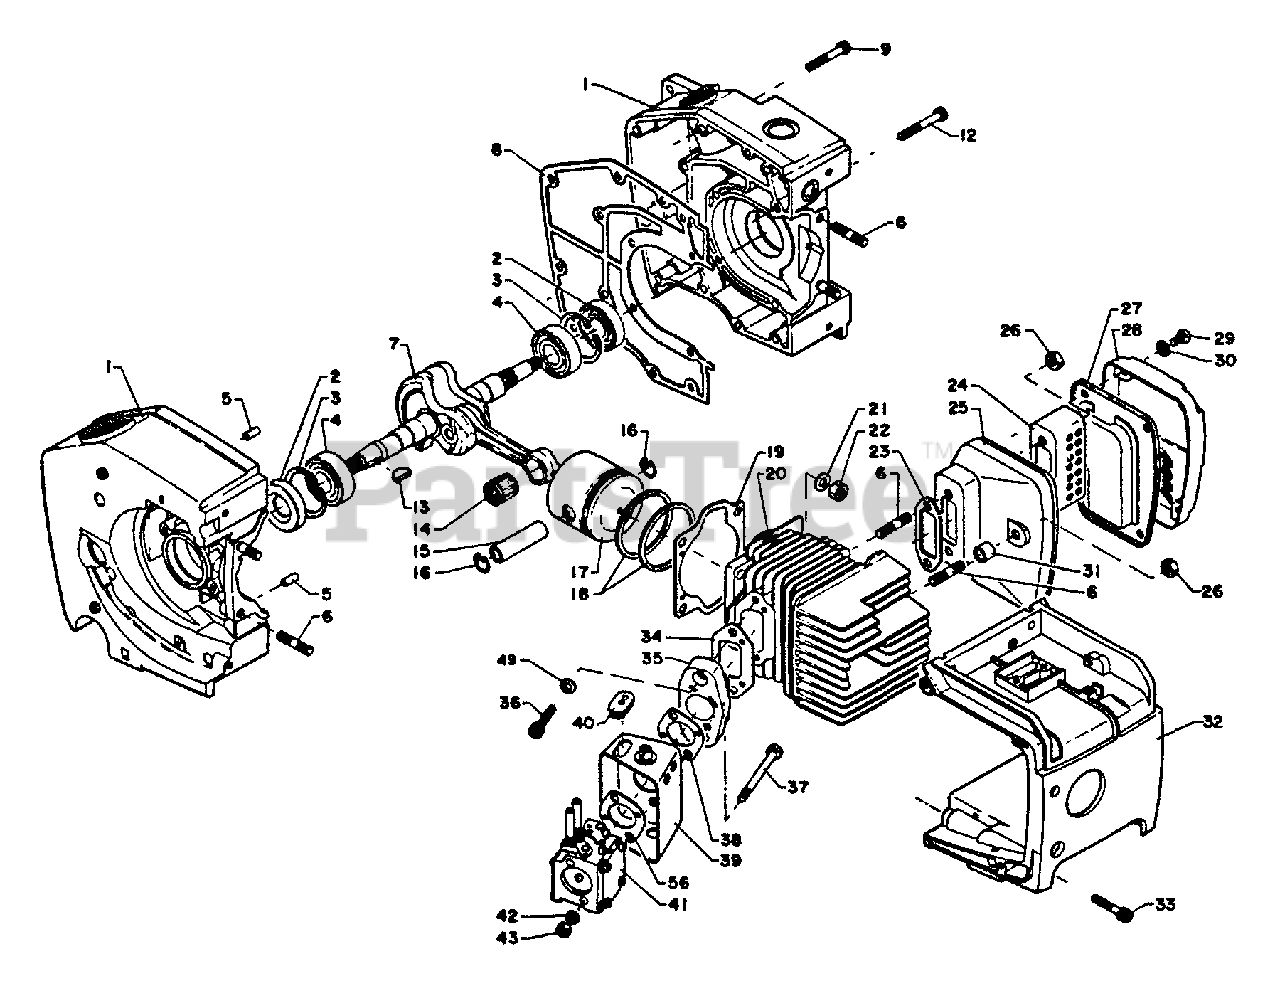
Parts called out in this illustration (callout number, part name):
1	CRANKCASE KIT
2	SEAL, OIL
3	RING, RETAINING - 35
4	BEARING, BALL - 6202
5	PIN - LOCATING
7	CRANKSHAFT ASSY
8	GASKET, CRANKCASE
9	SCREW - 5X30
12	SCREW - 5X35
13	KEY - 3X14
14	BEARING, NEEDLE
15	PIN, PISTON
16	RING, RETAINING
17	PISTON
18	RING, PISTON
19	GASKET, CYLINDER
20	CYLINDER
21	WASHER - 6
22	LOCKNUT - 6
23	GASKET, EXHAUST
24	BAFFLE, MUFFLER
25	MUFFLER
26	LOCKNUT - 6
27	PLATE
28	LID, MUFFLER
29	SCREW - 5X8
30	LOCKWASHER - 5
32	COVER, ENGINE
33	SCREW - 5X20
34	GASKET, INTAKE
35	CASE, CARBURETOR
37	BOLT
38	GASKET, INTAKE
39	CASE, CARBURETOR
40	GROMMET
41	CARBURETOR HS-166A
41	CARBURETOR
42	WASHER - 5
43	LOCKNUT - 5
56	GASKET
